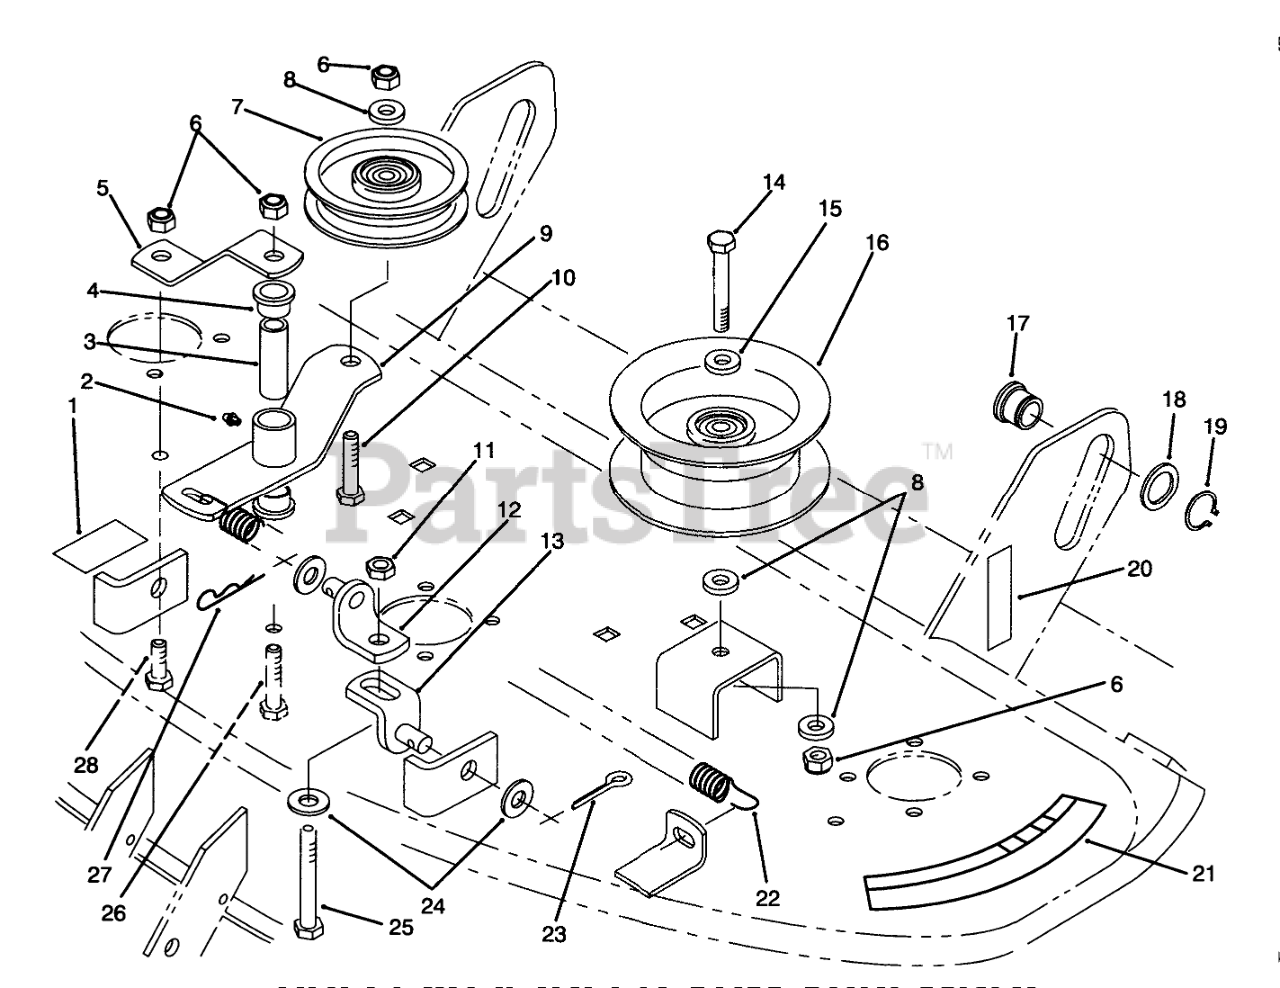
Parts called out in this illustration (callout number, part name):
1	DECAL-BELT INSTALL
2	FITTING-GREASE
3	SPACER
4	BUSHING
5	Strap-Brace
6	NUT-LOCK, NI
7	Pulley-Idler
8	WASHER-FLAT
9	Arm-Idler
10	SCREW-HH
11	NUT-JAM
12	BRACKET-LIFT, UPPER
13	BRACKET-LIFT, LOWER
14	SCREW-HH
15	WASHER
16	Pulley-Idler
17	ROLLER-LIFT
18	Washer
19	RING-RETAINING
20	Decal-Attach-A-Matic
21	DECAL - DANGER
22	SPRING - EXTENSION
23	PIN-COTTER
24	WASHER-FLAT
25	SCREW-HH
26	SCREW-HH
27	Hairpin
28	SCREW-HH
